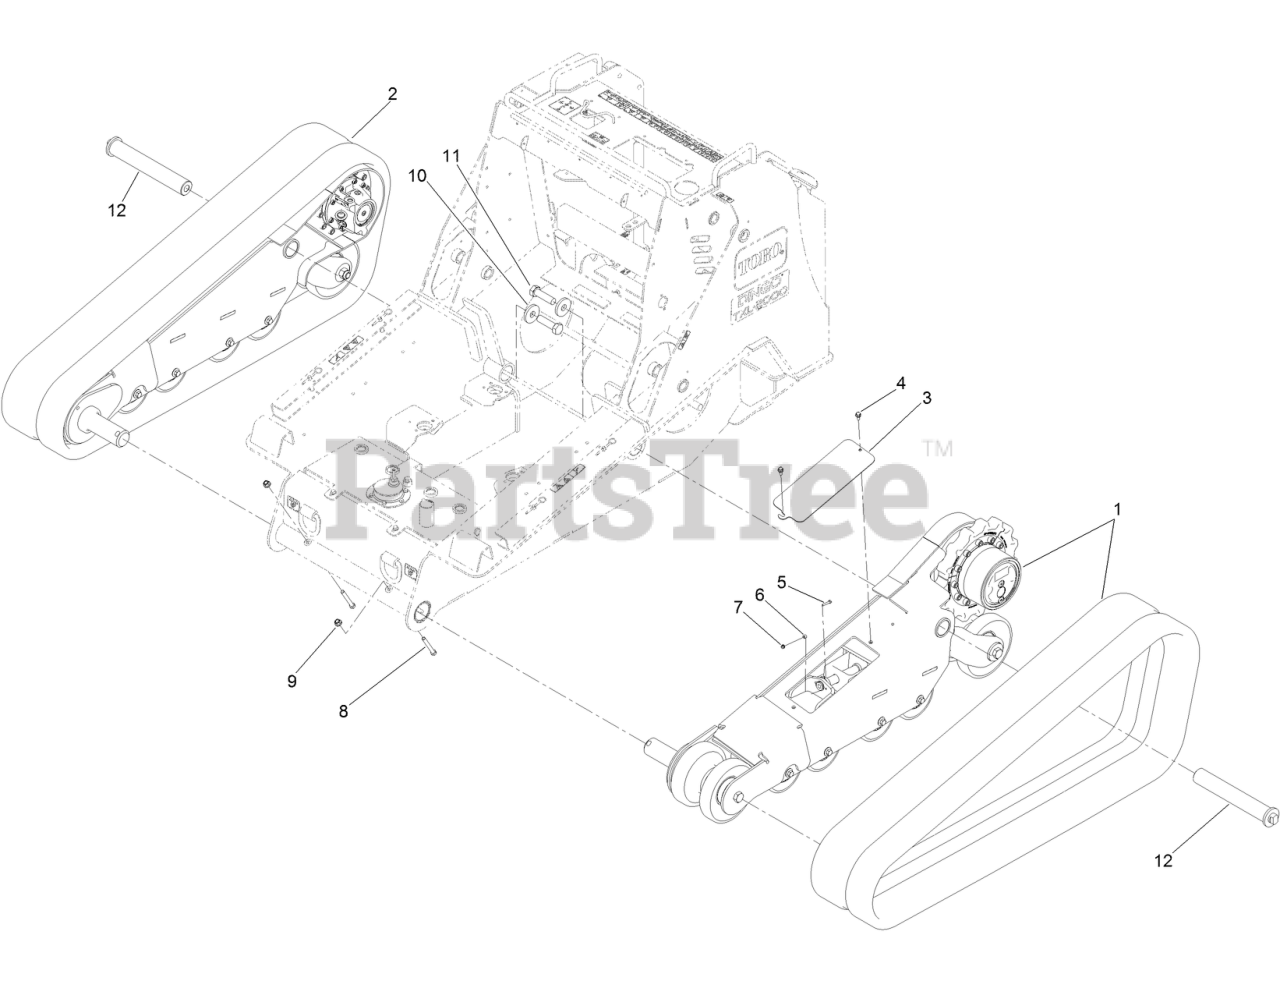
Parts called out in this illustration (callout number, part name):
1	LH TRACK ASM
2	RH TRACK ASM
4	SCREW-HHF
5	SCREW-HH
6	SPACER
7	NUT-HHF
8	BOLT-TAP
9	NUT-LOCK
10	WASHER-WHEEL
11	SCREW-CAP, HH
12	SHAFT-MOUNT, REAR
